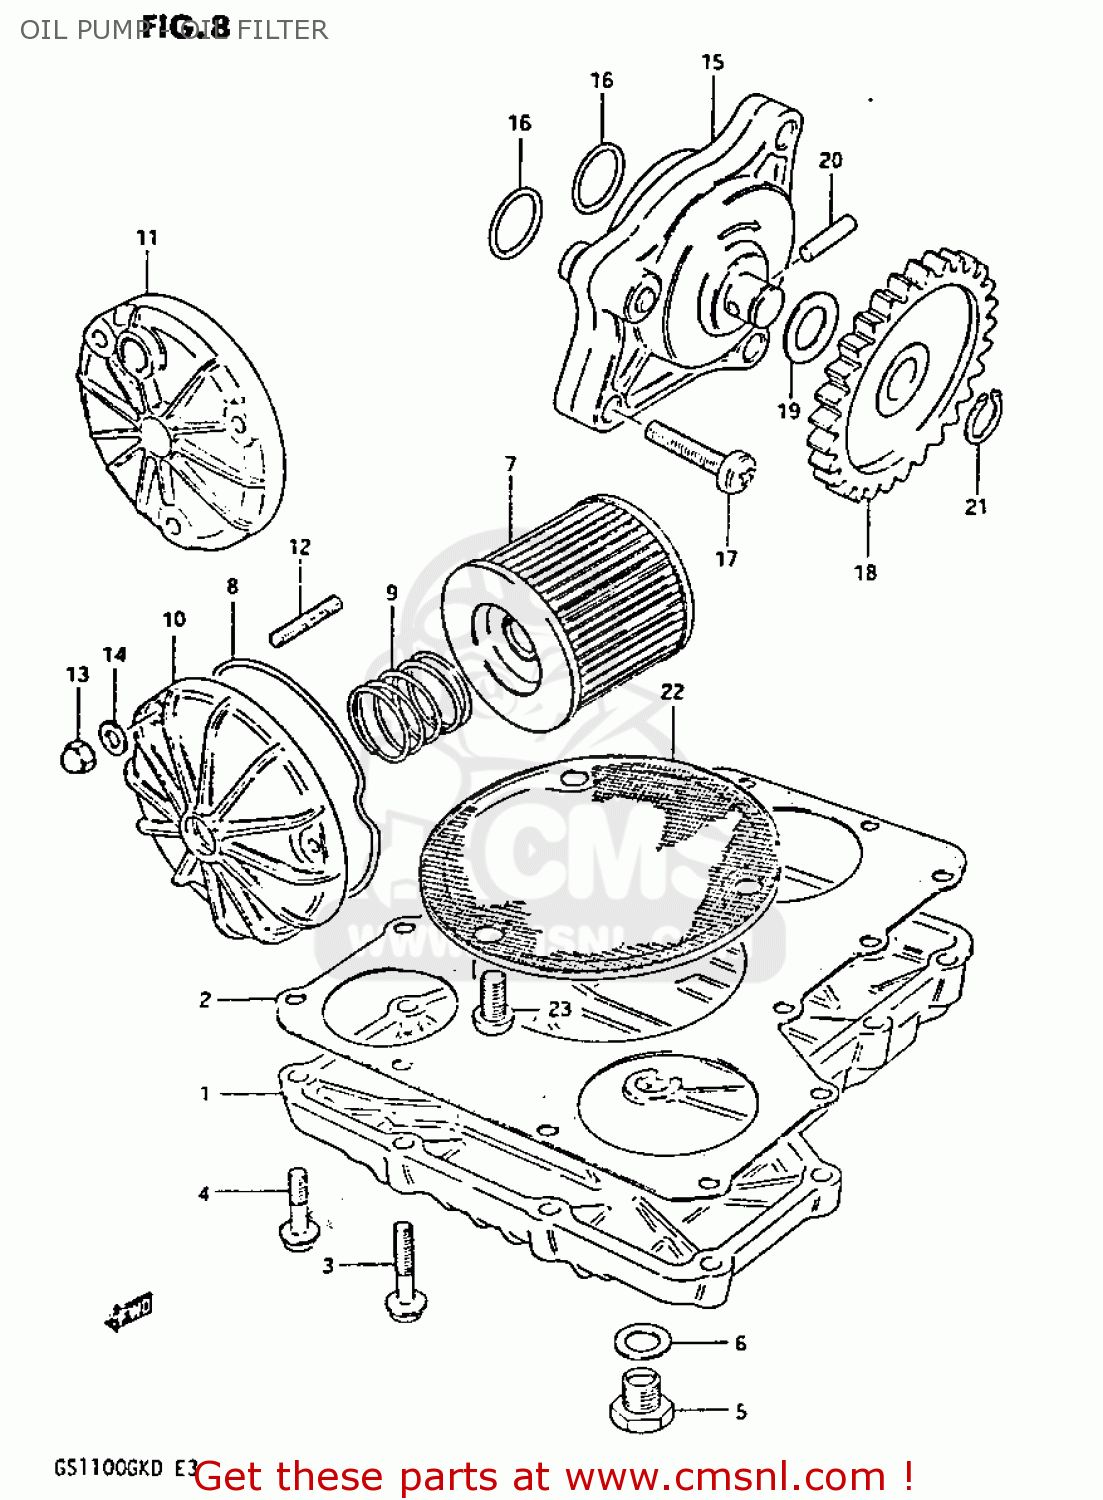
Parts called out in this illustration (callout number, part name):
1	PAN,OIL
2	GASKET,OIL PAN (NAS)
3	BOLT
4	BOLT
5	PLUG
6	GASKET(14X19.2X2) (NAS)
7	FILTER ASSY,ENGINE OIL
8	O RING,OIL FILTER CHAMBER CAP
9	SPRING
10	CAP,ENGINE OIL FILTER
11	CAP,OIL FILTER
12	STUD 6X20
13	NUT
14	WASHER
15	PUMP ASSEMBLY,ENGINE OIL
16	O RING(D:1.9,ID:13)
17	SCREW
18	GEAR,ENG OIL PUMP DRIVEN(NT:33
19	SHIM
20	PIN(4X15.8)
21	CIRCLIP
22	STRAINER,ENGINE OIL
23	SCREW 6X12
